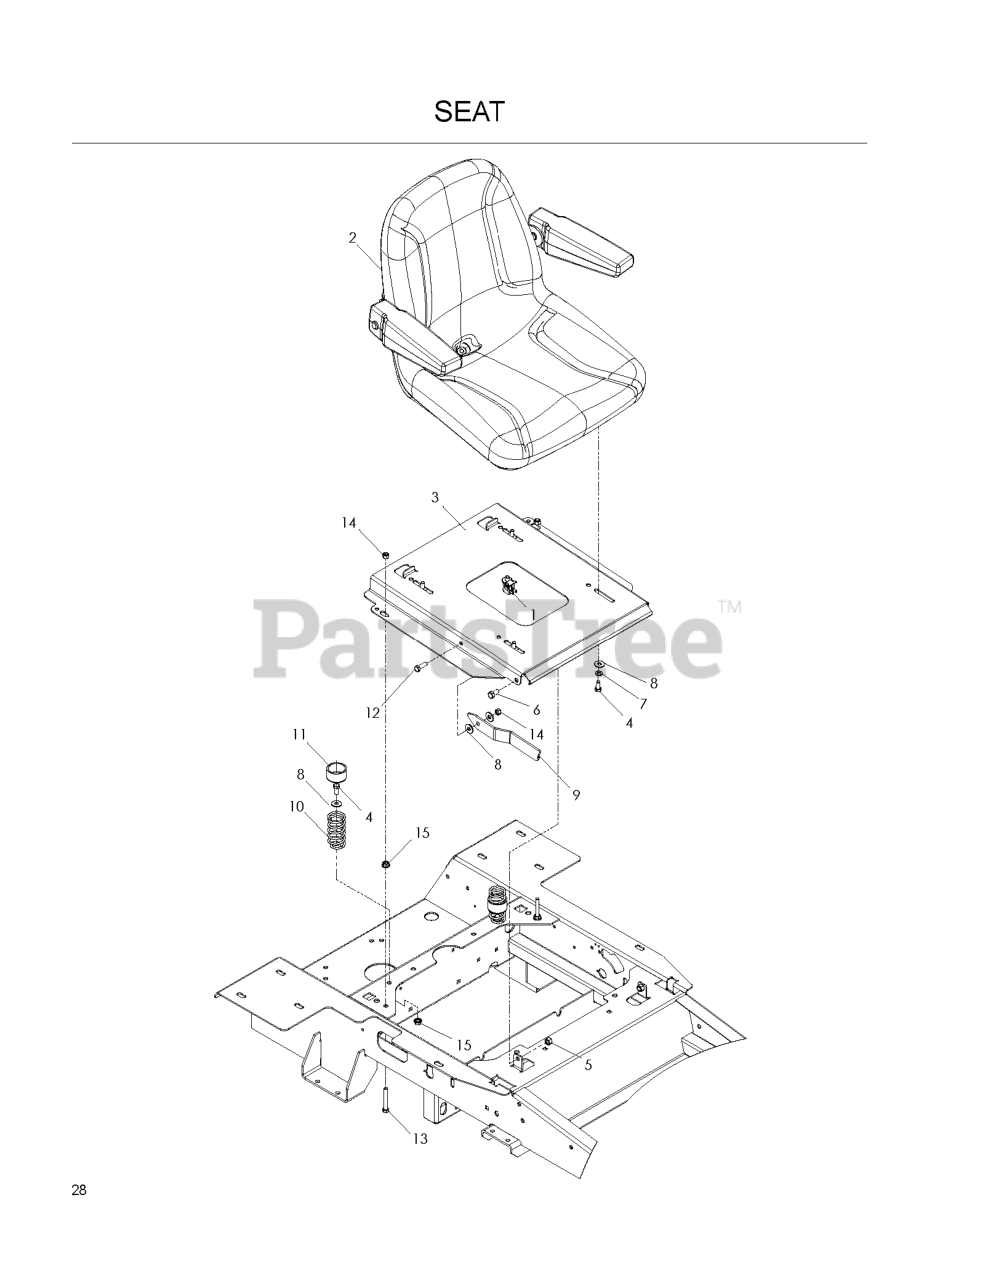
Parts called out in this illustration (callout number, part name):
1	SEAT SWITCH
2	SEAT W/ARMRESTS
3	PAN, SEAT, BLK
4	HCS 5/16C X 3/4
5	NUT 3/8-16 NYLOC
6	SCREW 3/8C X 3/4 HEX CAP
7	WASHER.LOCK.HVY.HLCL.SPR.5/16
8	WASHER 5/16 FLAT
9	ARM, PROP, SEAT
10	SEAT SPRING
11	SPRING CAP
12	HCS 5/16C X 1
13	TAP BOLT 5/16C X 2 1/4
14	NUT 5/16 NYLOC
15	NUT 5/16C WHIZ
